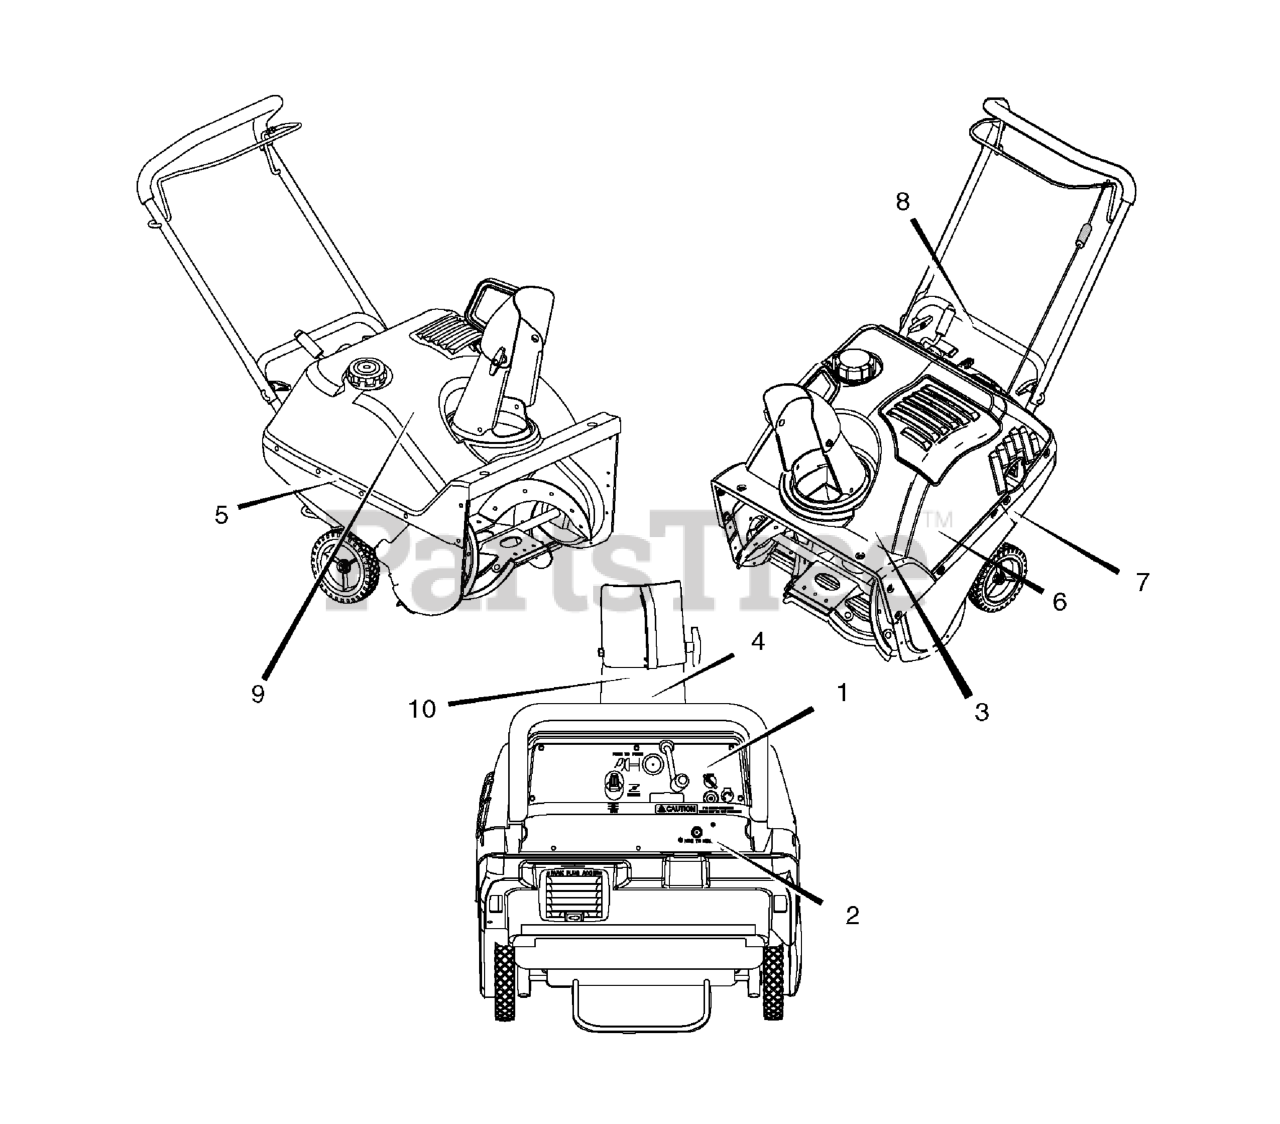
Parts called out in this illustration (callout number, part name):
1	DECAL, Control Panel English 22"
2	DECAL, Electric Start
3	DECAL, Danger Auger
4	DECAL, Danger Chute
5	DECAL, ST0522 Frontier R.H.
6	DECAL, ST0522 Frontier L.H.
7	DECAL, Hot Muffler
8	DECAL, Auger Control
9	DECAL, Briggs & Stratton
10	DECAL, Thrown Objects
